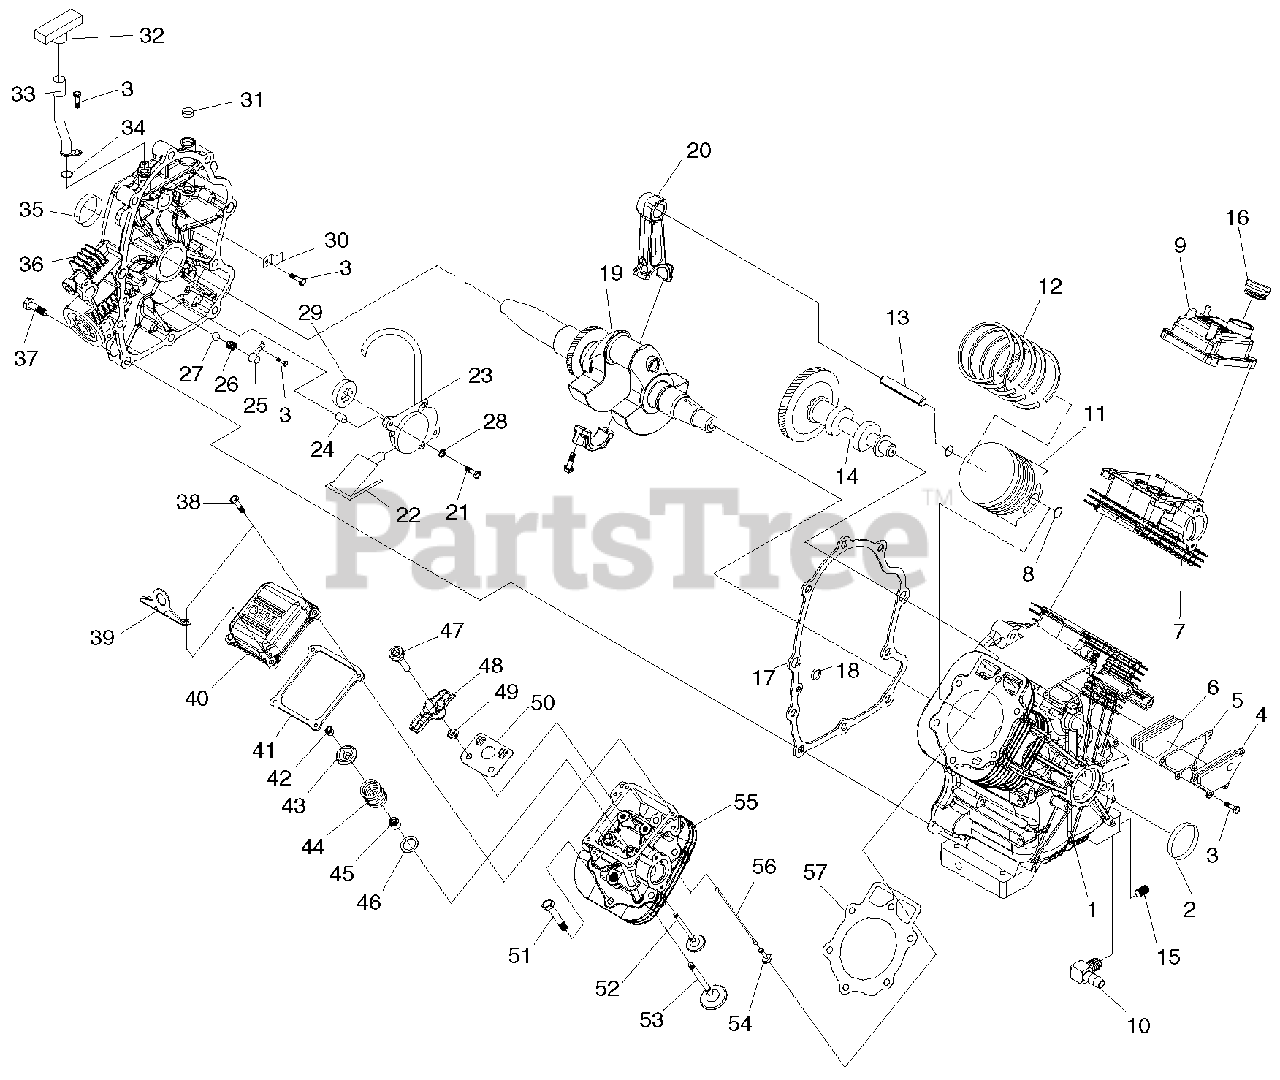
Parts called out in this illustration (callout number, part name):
1	ASSEMBLY, CRANKCASE HOUSING WITH SLEEVE
2	SEAL, 38 I.D. CRANKSHAFT
3	SCREW, TAPTITE M6-1.0 X 12 BP
4	ASSEMBLY, BREATHER
5	GASKET, BREATHER COVER
6	SEPARATOR, OIL BREATHER
7	ASSEMBLY, HEAD #1 G&S
8	RETAINER, PISTON PIN 20
9	ROCKER, COVER
10	BARBED EL 90 3/8NPT X 3/8
11	PISTON, LC
12	SET, PISTON RING 90MM
13	PIN PISTON D20
14	ASSEMBLY, CAMSHAFT & GEAR
15	PLUG STD PIPE 3/8 STEEL SQ HD
16	ASSEMBLY, OIL FILL CAP
17	GASKET, CRANK CASE
18	SEAL, OIL PASSAGE
19	ASSEMBLY, CRANKSHAFT HORIZONTAL DIRECT DRIVE (GT-990)
19	ASSEMBLY, CRANKSHAFT HORIZONTAL DIRECT DRIVE (GT-760)
20	ASSEMBLY, CONNECTING ROD (GT-990)
20	ASSEMBLY, CONNECTING ROD (GT-760)
21	SCREW SHC M6-1.0 X 50 G8.8
22	SCREEN, OIL PICKUP
23	ASSEMBLY, OIL PUMP
24	SLEEVE, SEAMED DOWEL 10 DIA.
25	COVER, OIL RELIEF
26	SPRING, OIL RELIEF
27	BALL, 1/2D OIL RELIEF
28	WASHER, LOCK RIB M6
29	GEROTOR, OUTER
30	CLAMP, OIL TUBE
31	PLUG-CRANKCASE GOVERNOR BORE
32	ASSEMBLY, DIPSTICK WITH HANDLE
33	TUBE, DIPSTICK O-RING, OIL CLR
34	O-RING, OIL CLR
35	SEAL, 42 I.D. CRANKSHAFT
36	ASSEMBLY, HOUSING COVER WITH SLEEVE
37	SCREW, HHFC M10-1.5 X 55
38	SCREW HHFC M6-1.0 X 20
39	HOOK, LIFTING
40	ROCKER, COVER
41	GASKET, VALVE COVER
42	KEEPER, VALVE SPRING
43	RETAINER, VALVE SPRING
44	SPRING, VALVE
45	SEAL, VALVE STEM D7
46	WASHER, VALVE SPRING
47	STUD, D20 PIVOT BALL
48	ARM, SOLID ROCKER
49	NUT, HEX M8-1.0 GB YELLOW CHROM
50	PLATE, PUSH ROD GUIDE
51	SCREW HHFC M8-1.25 X 65
52	VALVE, EXHAUST
53	VALVE, INTAKE
54	TAPPET, SOLID
55	ASSEMBLY, HEAD #2 G&S
56	PUSHROD, 139.6 VERTICAL
57	GASKET, HEAD
58	KIT GEAR COVER
59	KIT GASKET
60	KIT PISTON & RINGS
61	KIT BREATHER ASSEMBLY
62	KIT HEAD ASSEMBLY CYLINDER 1
63	KIT HEAD ASSEMBLY CYLINDER 2
64	KIT OIL RELIEF
